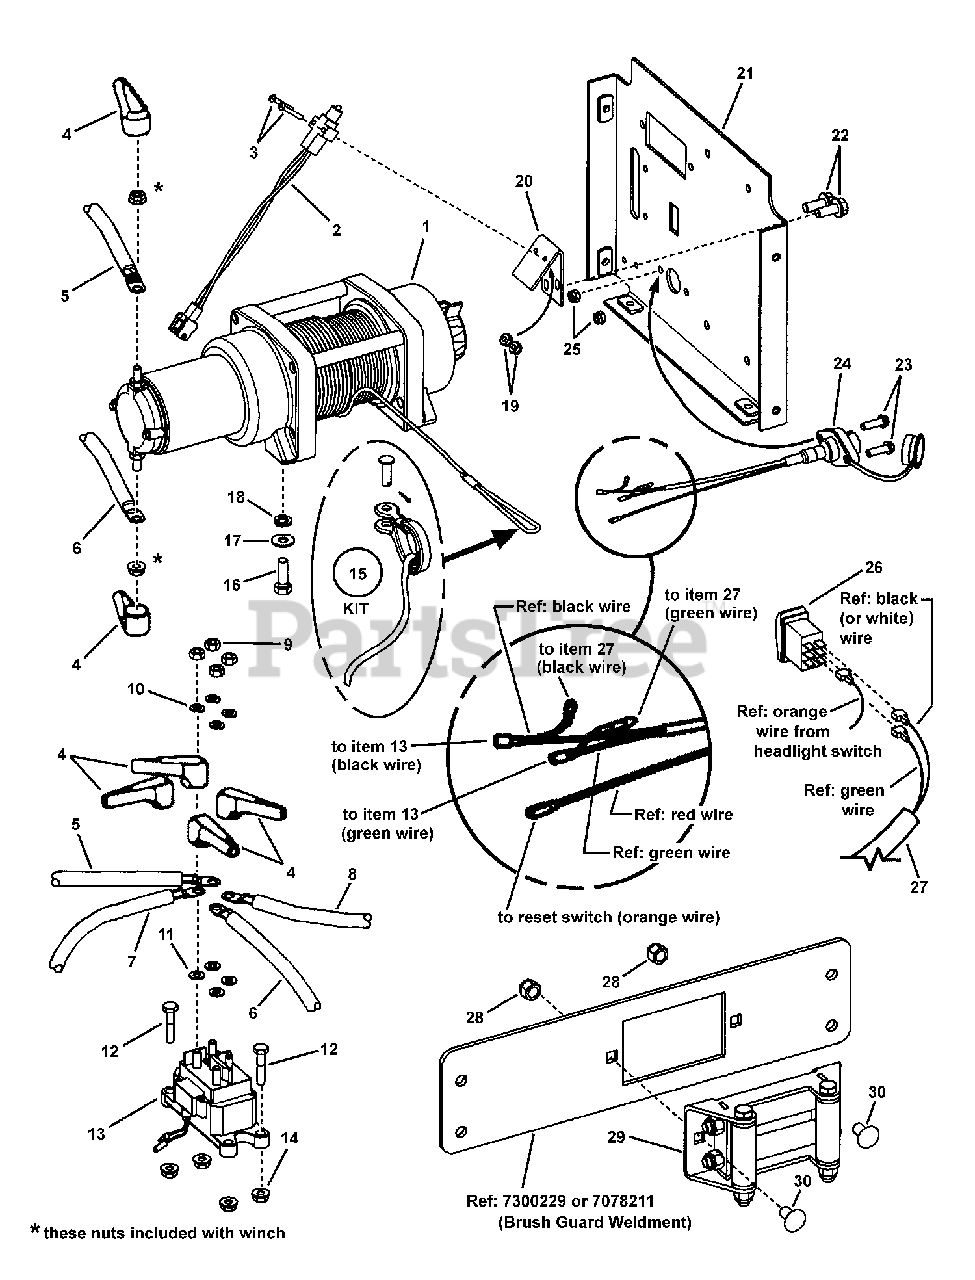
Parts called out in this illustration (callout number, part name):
1	WINCH, Warner 2.5 C.I.
1	BOLT, 1/4-20 X 5/8 GD5 YZ
2	SWITCH, Throttle Interlink (NO)
2	NUT, 1/4-20 HEX NYLOCK FLANGE
3	SCREW, #6-32 Truss Head, Slotted
3	BOLT, 3/8-16 X 2-1/4 GD5 YZ
4	BOOT, Terminal Winch
4	NUT, 3/8-16 HEX NYLOCK FLANGE
5	WIRE, Yellow, 6 Ga. 71" long
5	PIN, CLEVIS, 5/16 X 1 YZ
6	WIRE, Blue, 6 Ga. 71" long
6	PIN, HAIR, .0585 X 1-1/8, 1/4 EYE, YZ
7	WIRE, Black, 6 Ga. 18" long
7	COLLAR, 5/16" SET
8	WIRE, Red, 6 Ga. 18" long
8	SPRING, COMPRESSION
9	NUT, 1/4-20 Hex
9	SPRING; CLUTCH HANDLE
10	WASHER, 1/4" Split Lock
10	WASHER, 5/16 USS
11	WASHER, 1/4" Flat
11	NUT, 5/16-24 HEX NYLON LOCK
12	SCREW, 1/4-20 x 1-1/4" Hex Head Cap
12	NUT, 5/16-24 JAM
13	CONTACTOR, 12V Winch
14	NUT, 1/4-20 Hex Flange Lock, GR 5
15	KIT, Winch Hook
16	SCREW, 5/16-18 x 1" Hex Head Cap, GR 5
17	WASHER, .31 x .75 x .08 Flat
18	WASHER, .32 x .58 x .08 Split Lock
19	NUT, #6-32 Hex Nyloc
20	THROTTLE ANCHOR, Front
